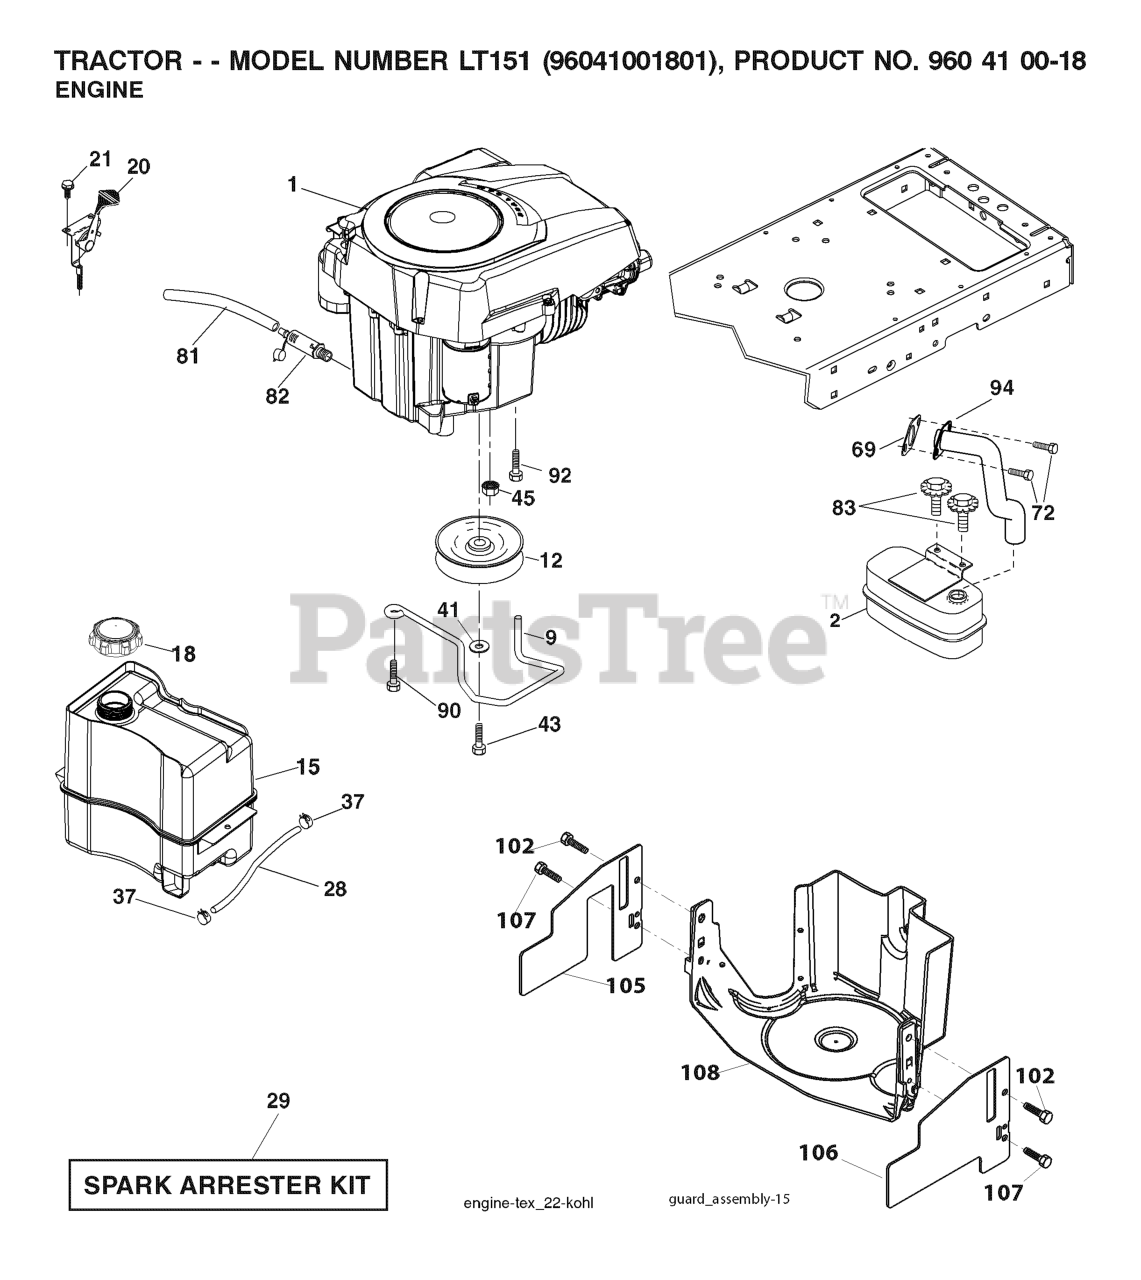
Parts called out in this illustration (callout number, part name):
2	MUFFLER.SINGLE.CYL.KOHL/B&S
9	KEEPER.BELT.ENGINE.3.25 (3 2)
12	PULLEY ENGINE
15	RP TANK FUEL FRT 1.5 GAL
18	FUEL CAP
20	CONTROL.TH/CK.C.
21	SCREW
28	LINE.FUEL.20
29	KIT.SPARK ARRESTOR 794945 B&S
37	HOSE CLAMP
41	LOCKWASHER
43	BOLT HEX 7/16-20X4-1/4"
45	NUT
81	TUBE, DRAIN OIL ASM.
82	PLUG DRAIN OIL EASY
83	BOLT.5/16-18UNCX3/4 W/SEMS.BLK
86	NUT.HEX.FLANGE.TOPLOCK
90	SCREW 3/8-16X1
92	SCREW 3/8-16X1
94	RP.TUBE.EXHAUST.KOHL.COURAGE
96	WASHER
97	SCREW HEXWSHR 1/4-20X3/4
